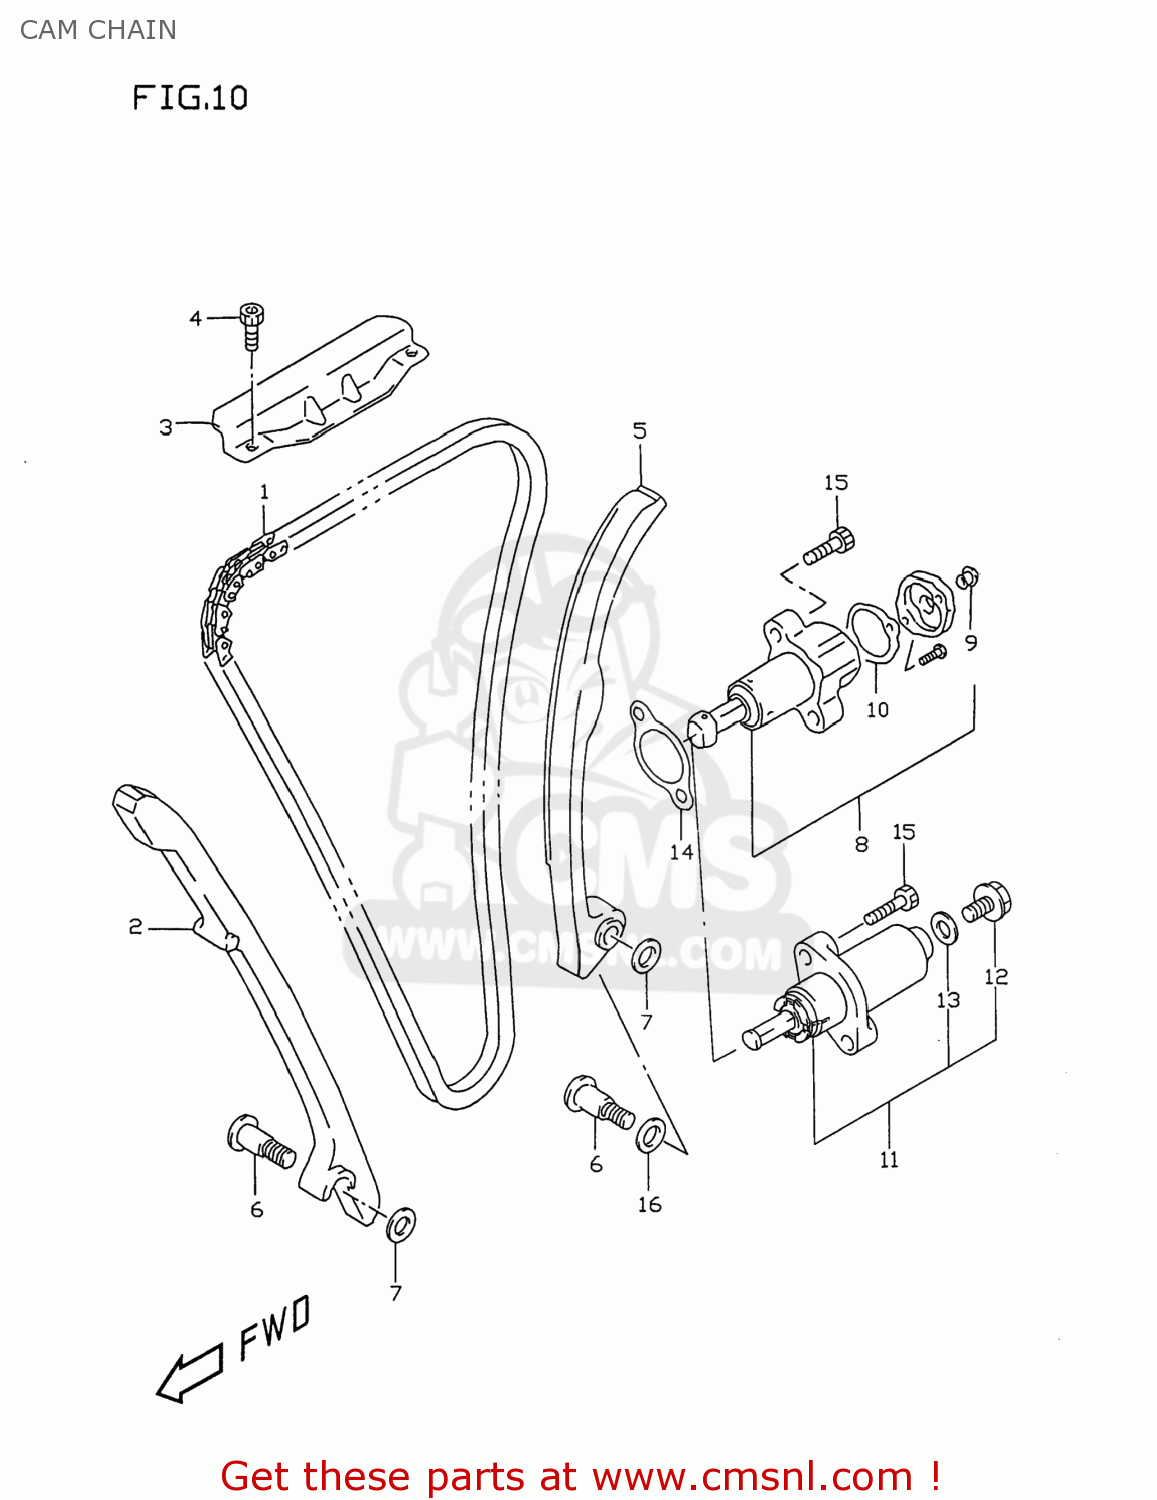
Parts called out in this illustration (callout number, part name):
1	CHAIN,CAMSHAFT DRIVE
2	GUIDE,CAM CHAIN NO.1
3	GUIDE,CAM CHAIN NO.2
4	BOLT,STRANGER
5	TENSIONER,CAM CHAIN
6	BOLT,CAM CHAIN TENSIONER/GUIDE
7	WASHER
8	ADJUSTER ASSY,TENSIONER
9	PLUG,ADJUSTER
10	GASKET,ADJUSTER CAP (NAS)
11	ADJUSTER ASSEMBLY,TENSIONER
12	PLUG,TENSIONER ADJUSTER
13	GASKET,TENSIONER ADJUSTER
14	GASKET,TENSIONER ADJUSTER (NAS)
15	BOLT,CL.COVER
16	WASHER
